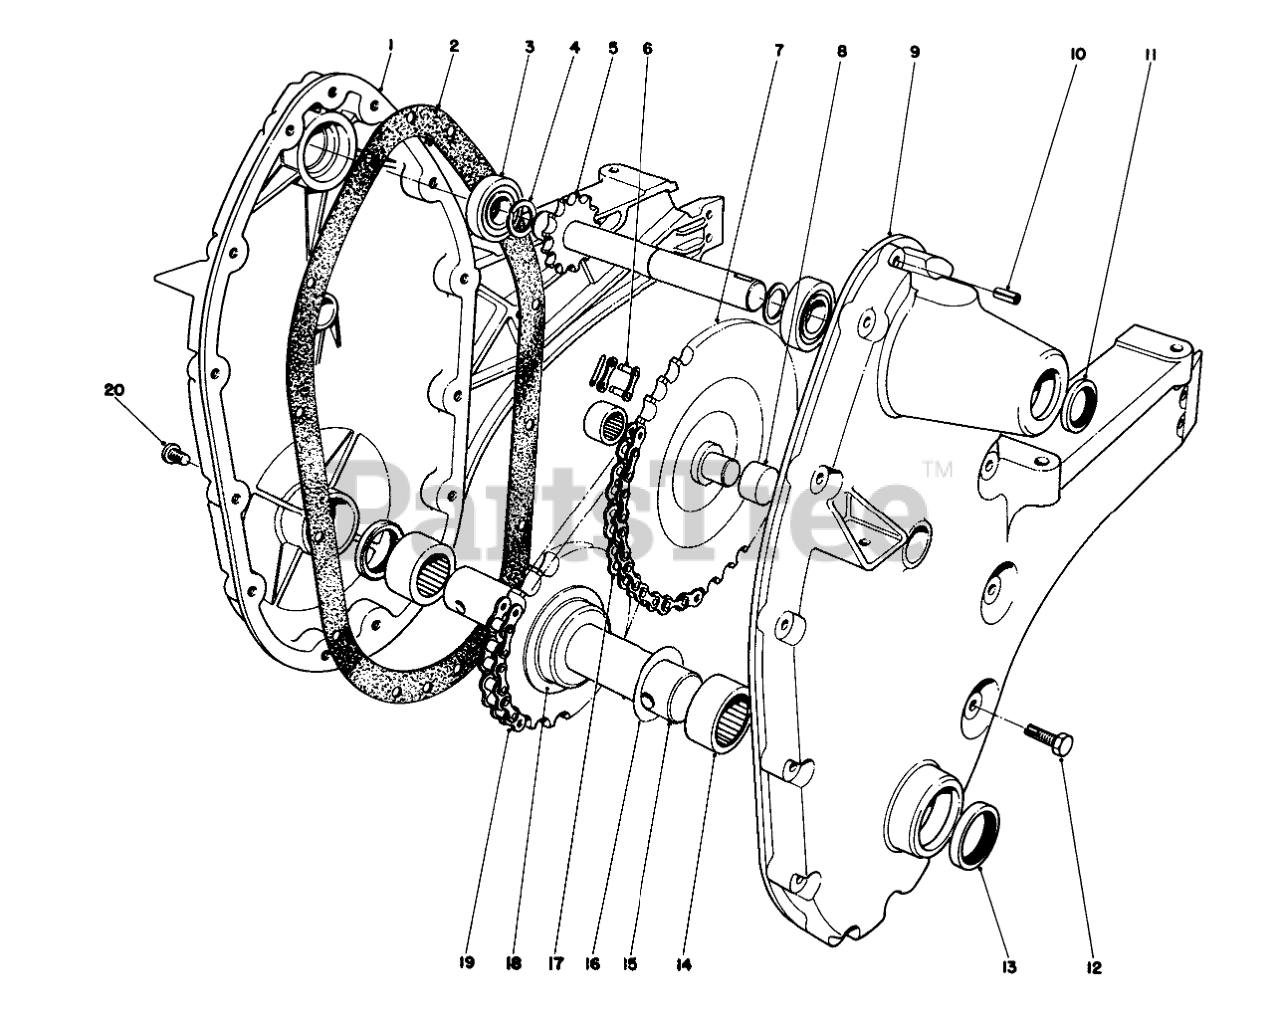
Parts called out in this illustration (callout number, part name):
1	Chain Case R H.
2	GASKET TILLER
3	BALL BRG
4	5/8X030 EX MED RING
5	Upper Shaft
6	LINK-CONNECTING, NO. 35
7	Sprocket Cluster
8	NEEDLE BRG
9	Chain Case L.H.
10	PIN-ROLL
11	SEAL-OIL
12	SCREW-HWH, TAP
13	SEAL-OIL
14	NEEDLE BRG
15	TINE SHAFT
16	Washer
17	Roller Chain
18	Cup Spacer
19	Roller Chain
